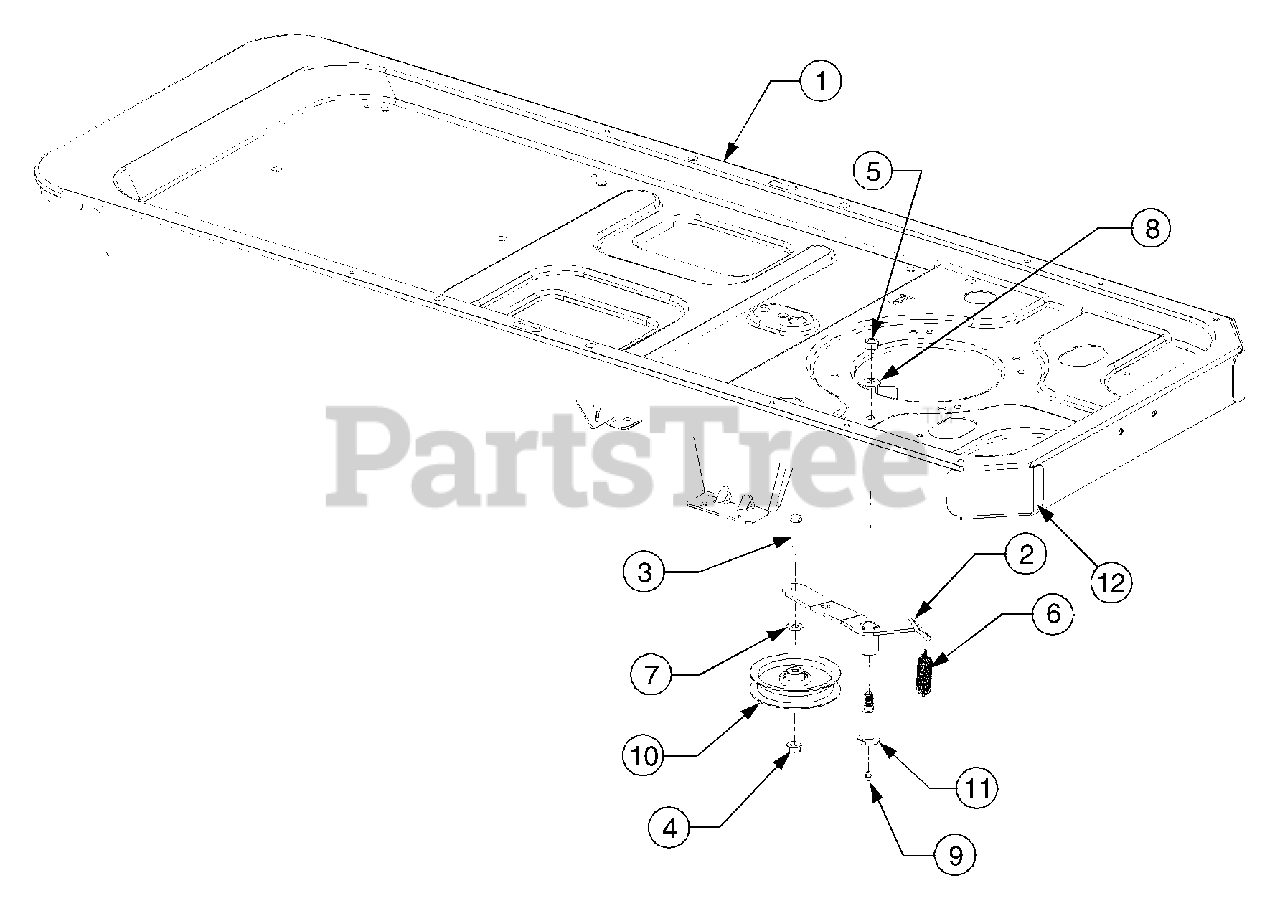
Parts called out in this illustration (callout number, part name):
4	Nut, Hex Flange Lock, 3/-16 GRF
5	Nut, Hex Lock, 7/16-14 GRA
6	Spring, Extension, .75 x 5.06
7	Washer, Flat, .406 x .875 x .059
8	Washer, Flat, .45 x 1.25 x .164 HT
9	Fitting, Lube, 3/16 Drive
10	Pulley, Idler, 4.08 Dia.
11	Screw, Shoulder, .68 x 1.59
